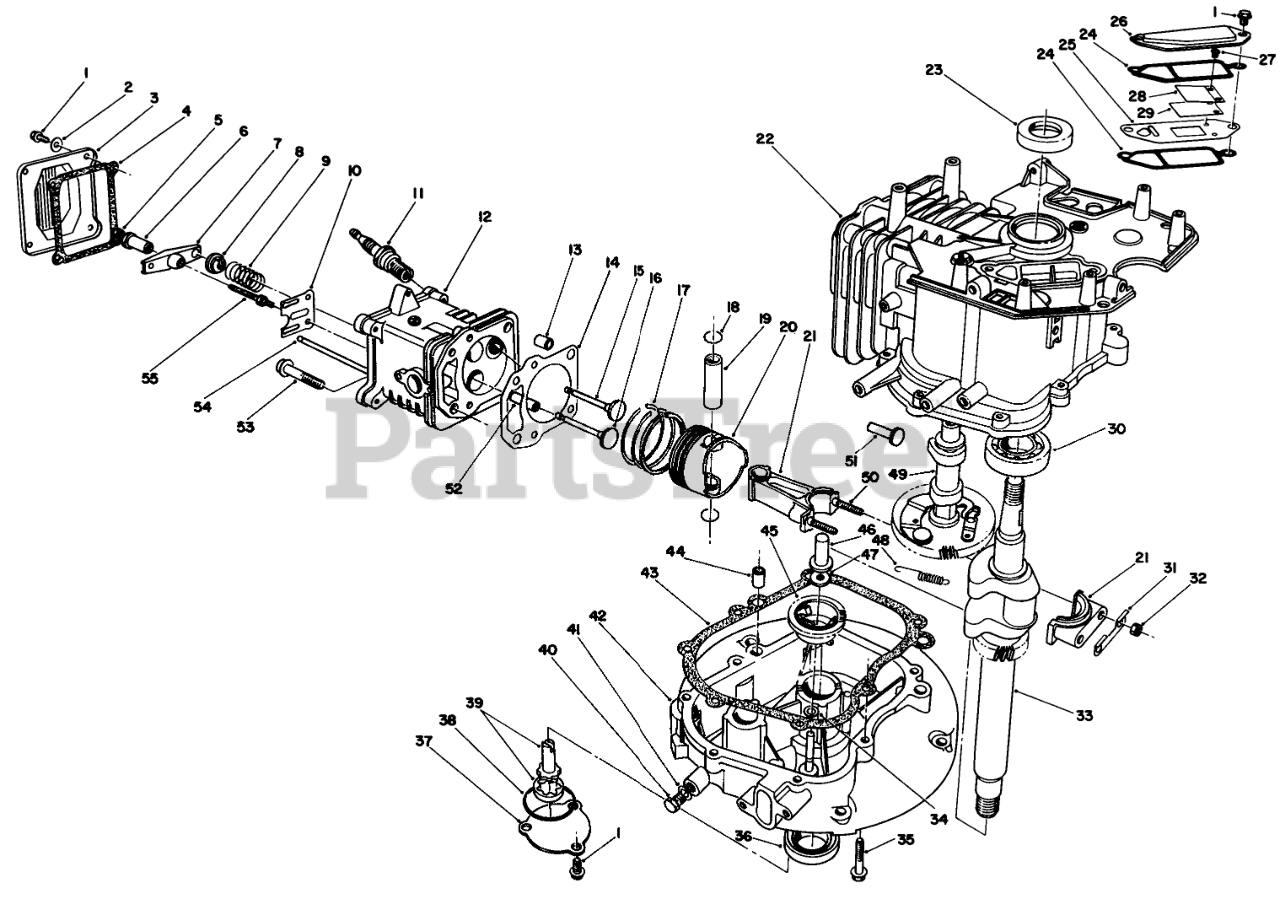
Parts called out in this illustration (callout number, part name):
2	WASHER
3	COVER
4	GASKET
6	PIVOT
8	RETAINER
9	SPRING
10	GUIDE
11	SPARK PLUG
12	Head-Cylinder (Incl. Ref. #52)
14	Gasket-Cylinder Head
15	VALVE-INTAKE
16	VALVE-EXHAUST
17	RING SET
18	CIRCLIP
20	PISTON
21	Connecting Rod Assembly (Incl. Ref. #31, 32, & 50)
22	Block-Engine (Incl. Ref. #23, & 30)
24	GASKET
25	Plate-Breather
26	COVER
27	Screw-Reed Valve
28	Retainer-Reed Valve
29	Valve-Reed
30	BEARING
31	Plate-Lock
33	CRANKSHAFT
34	WASHER
37	COVER
38	O-RING
39	OIL PUMP
40	Plug-Oil Drain
41	GASKET
42	Crankcase
43	GASKET
45	GOVERNOR FLYWEIGHT ASM
46	PLUNGER
47	WASHER
48	SPRING
49	Camshaft Assembly (Incl. Ref. #48)
51	TAPPET
52	GUIDE
